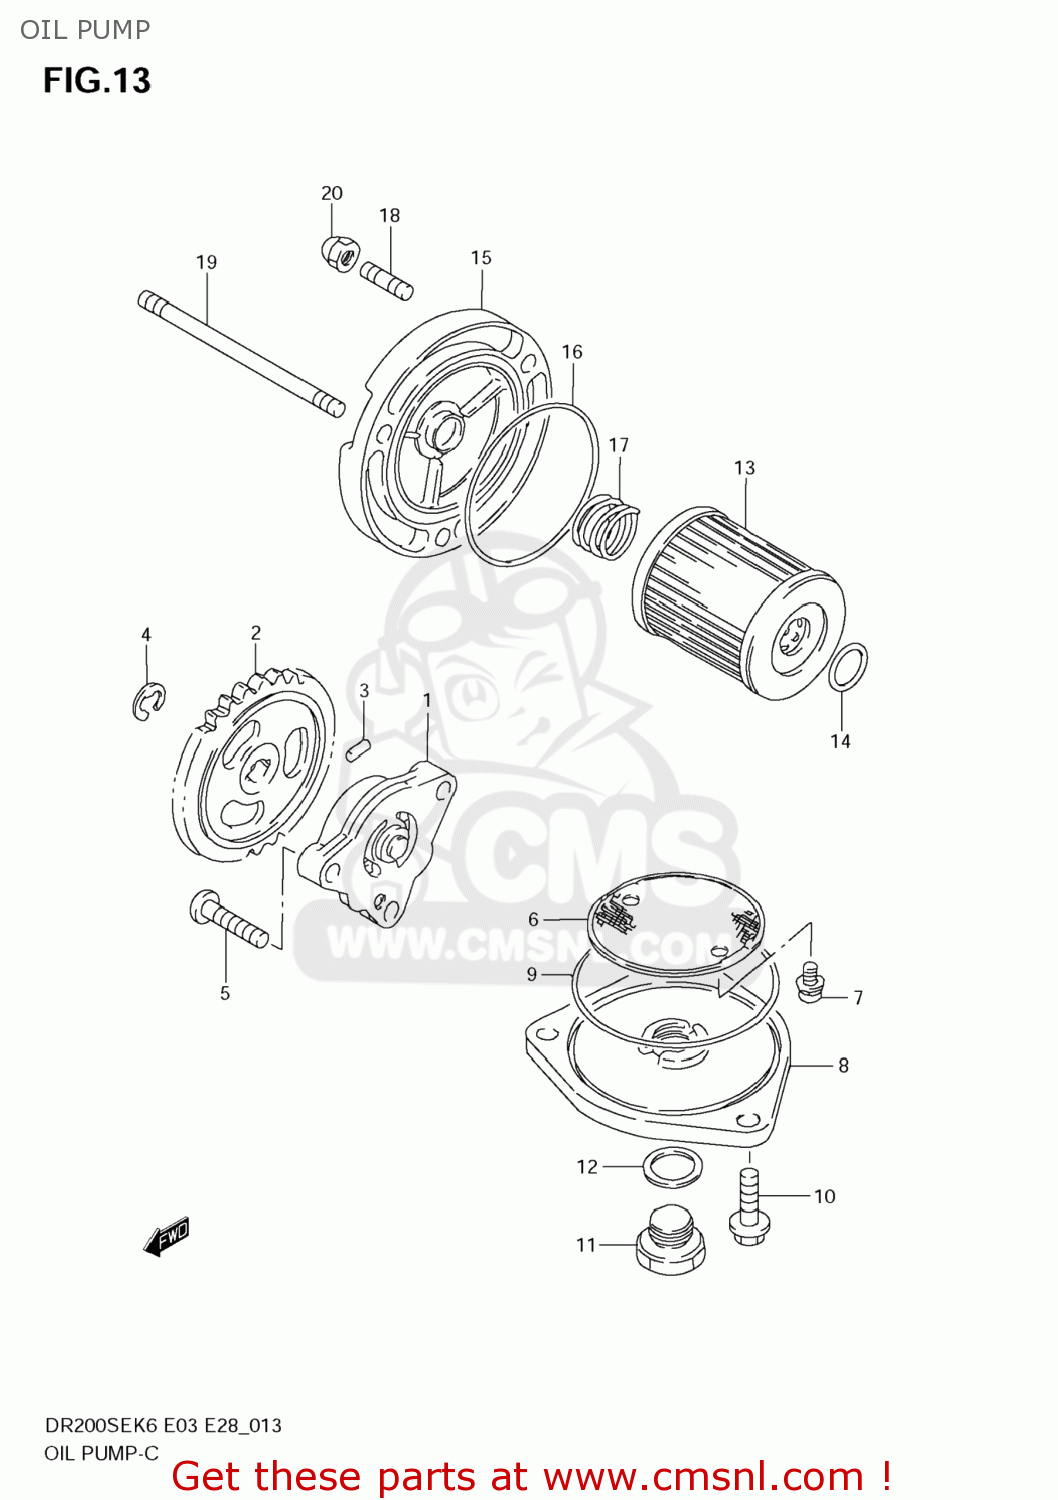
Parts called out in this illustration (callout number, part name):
1	PUMP ASSY,ENGINE OIL
2	GEAR,OIL PUMP DRIVEN
3	PIN(2.5X11.8)
4	E RING
5	SCREW
6	STRAINER,ENGINE OIL
7	SCREW
8	CAP,OIL STRAINER
9	O RING(D:2.4,ID:60.5)
10	BOLT
11	PLUG(14X12)
12	GASKET(13.8X18.8X4.8) (NAS)
13	FILTER ASSY,ENGINE OIL
14	O RING(D:1.9,ID:13)
15	CAP,OIL FILTER
16	O RING(D:2.4,ID:52.6)
17	SPRING
18	BOLT,STUD
19	BOLT,STUD
20	NUT
